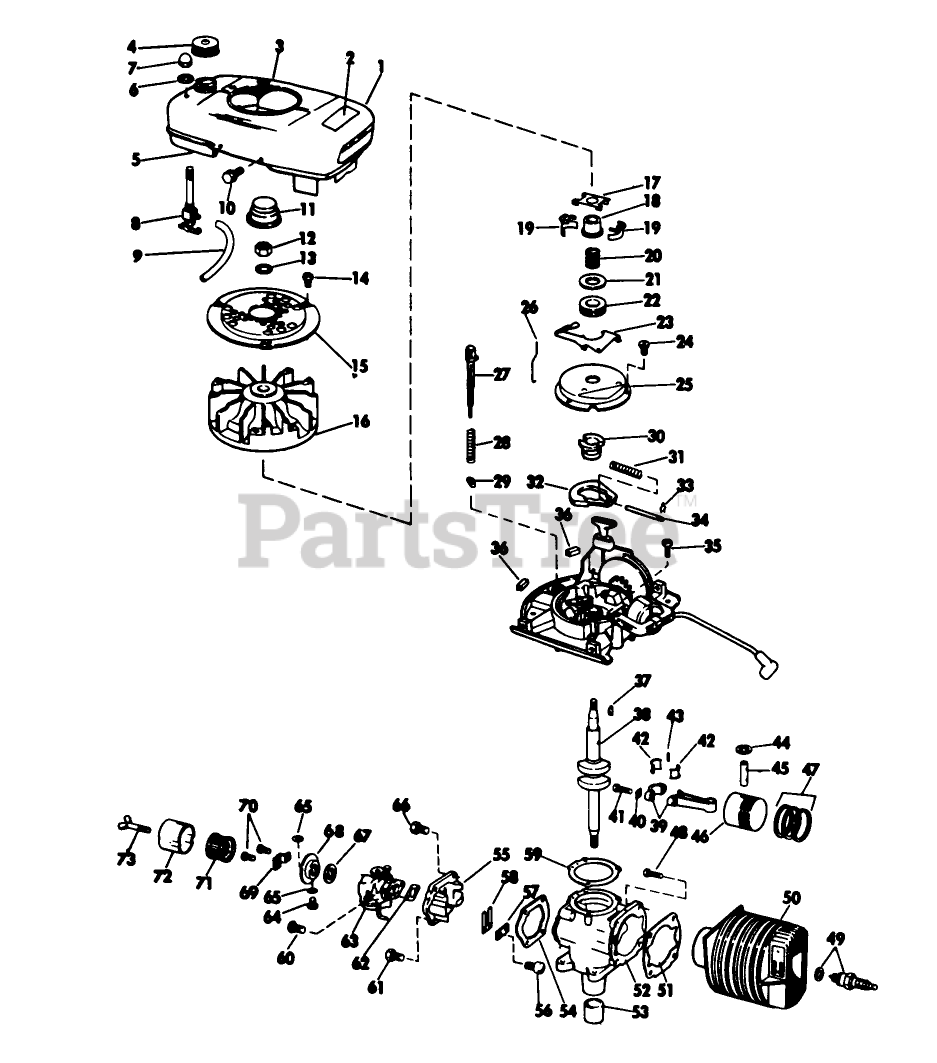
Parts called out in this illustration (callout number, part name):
7	PALNUT S
8	VALVE&SCREEN SM
10	SCREW S
12	NUT
15	Screen-Flywheel
17	YOKE S
18	COLLAR S
22	THRUST COLLAR S
23	LEVER-GOVERNOR S
24	SCREW S
25	DUST COVER S
26	ROD S
28	SPRING S
30	SPARK ADV. S
31	SPARK ADV. SPRING S
32	FLYWEIGHT S
33	SPARK ADJ. SPRING
34	PIN,SPARK ADV. S
41	SCREW
42	LINER ASM
44	RING-RETAINING
51	GASKET S
57	PLATE-BACKUP, REED
59	GASKET S
61	SCREW S
62	GASKET S
66	SCREW S
67	GASKET S
